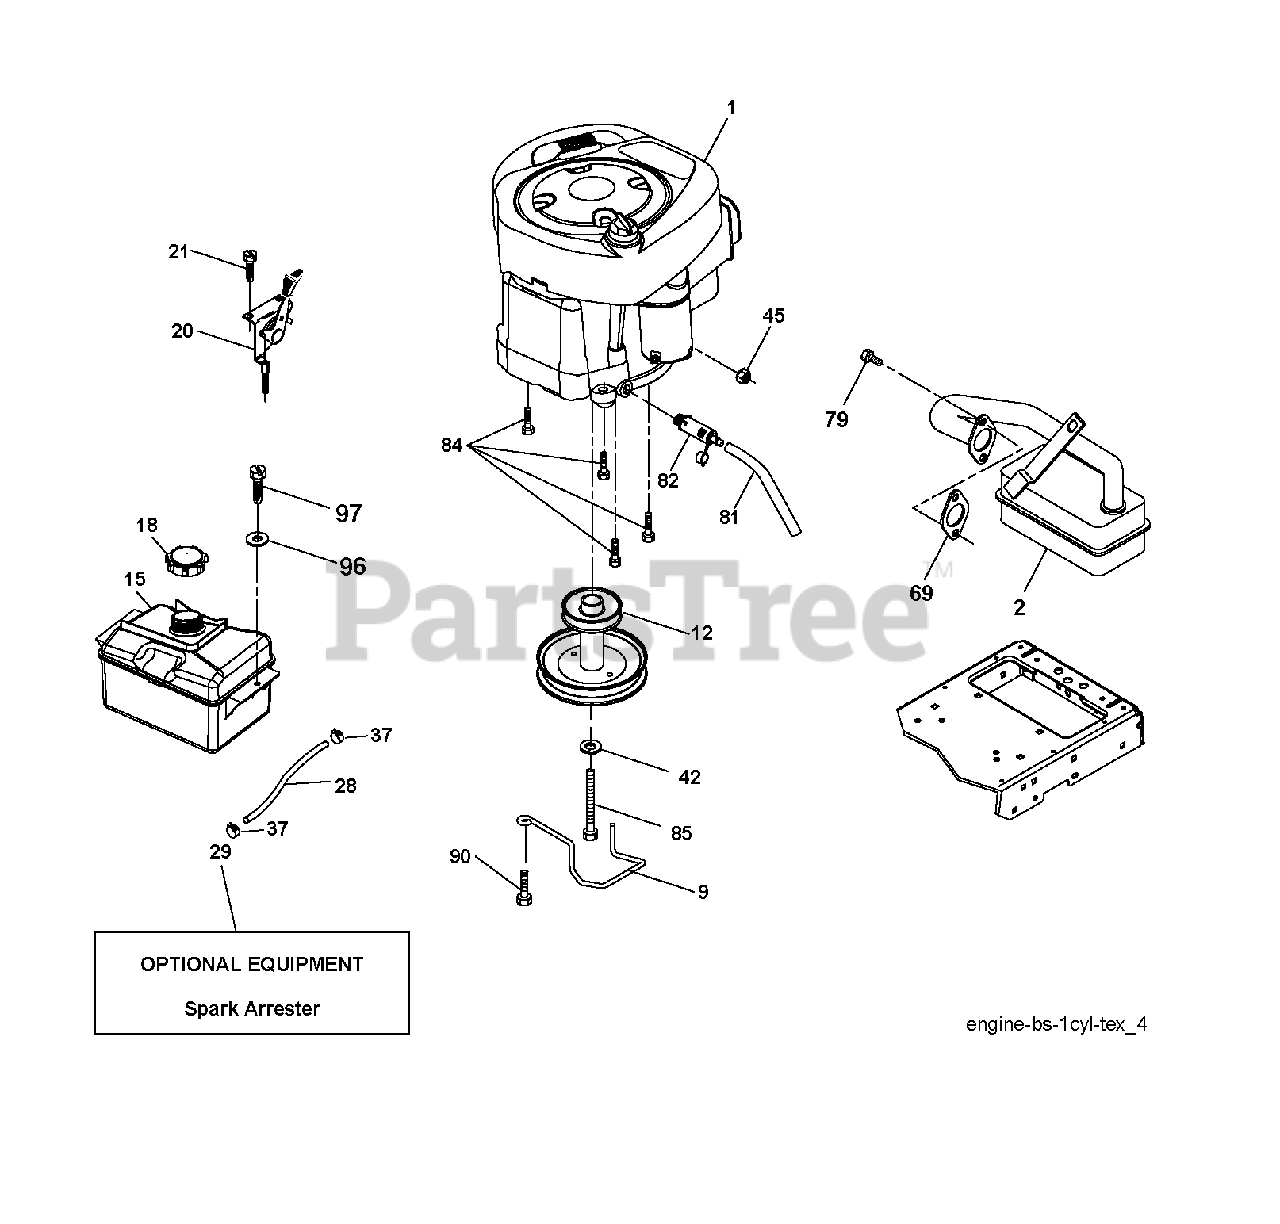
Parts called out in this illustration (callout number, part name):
9	KEEPER.BELT.ENGINE.3.25
12	PULLEY ENGINE
15	TANK FUEL FRT 1.5 GAL
18	FUEL CAP
20	CONTROL.TH/CK.C.
21	SCREW.#10 X 0.750.BOS THREAD
28	LINE.FUEL.20
29	ARRESTER SPARK (OPTIONAL)
37	HOSE CLAMP
42	LOCKWASHER
45	NUT
69	REPL BY 532 27 22-93
79	SCREW.SOCKET HD.5/16-1
81	TUBE, DRAIN OIL ASM.
82	PLUG DRAIN OIL EASY
84	SCREW.3/8-16
85	BOLT HEX 7/16-20X4-1/4"
90	SCREW 3/8-16X1
97	SCREW HEXWSHR 1/4-20X3/4
